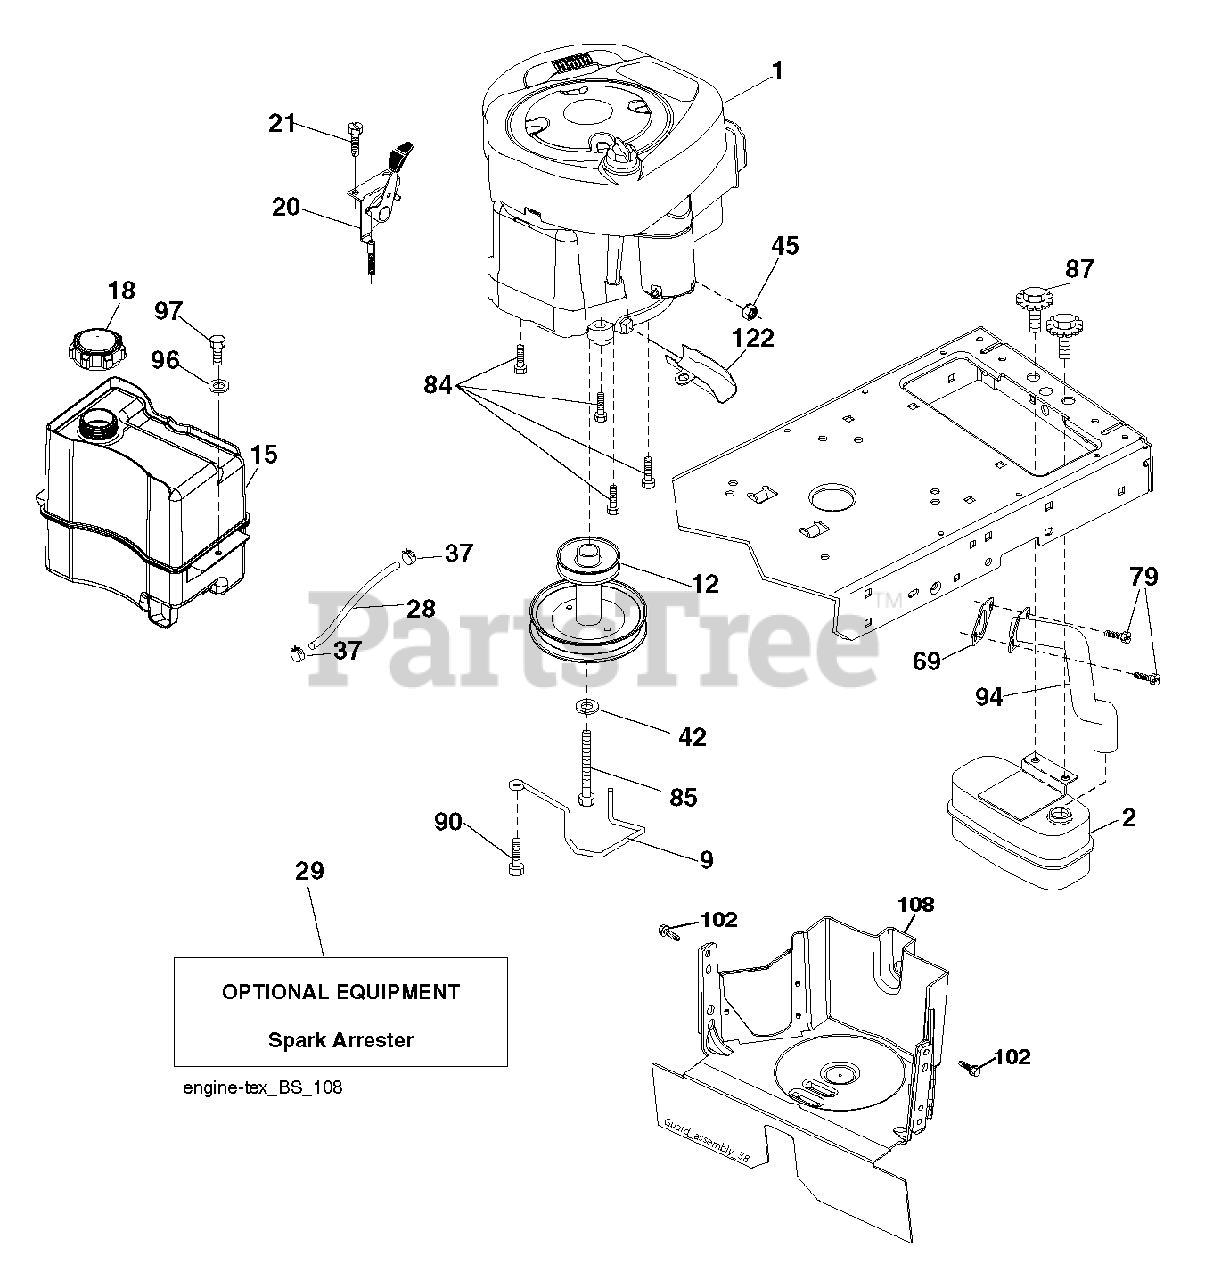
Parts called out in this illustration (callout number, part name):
2	MUFFLER.SINGLE.LRG.BRIGGS.KOHL
9	KEEPER BELT ENGINE
12	PULLY ENGINE
15	FUEL.TANK.ASM.NON-EPA
18	CAP ASM.FUEL.2.25"FR.
20	CONTROL.TH/CK.C.
21	SCREW.#10 X 0.750.BOS
28	LINE.FUEL.20
29	KIT.SPARK ARRESTOR 794945 B&S
37	HOSE CLAMP
42	LOCKWASHER
45	NUT
69	REPL BY 532 27 22-93
79	SCREW.SOCKET HD.5/16-1
84	SCREW.3/8-16
85	BOLT HEX 7/16-20X4-1/4"
87	BOLT, 5/16-18 X 1 3/4
90	SCREW 3/8-16X1
94	EXHAUST.TUBE.B&S.28/31
97	SCREW HEXWSHR 1/4-20X3/4
102	SCREW 5/16-18X1
108	COVER PULLEY
122	EXTENSION DRAIN OIL
